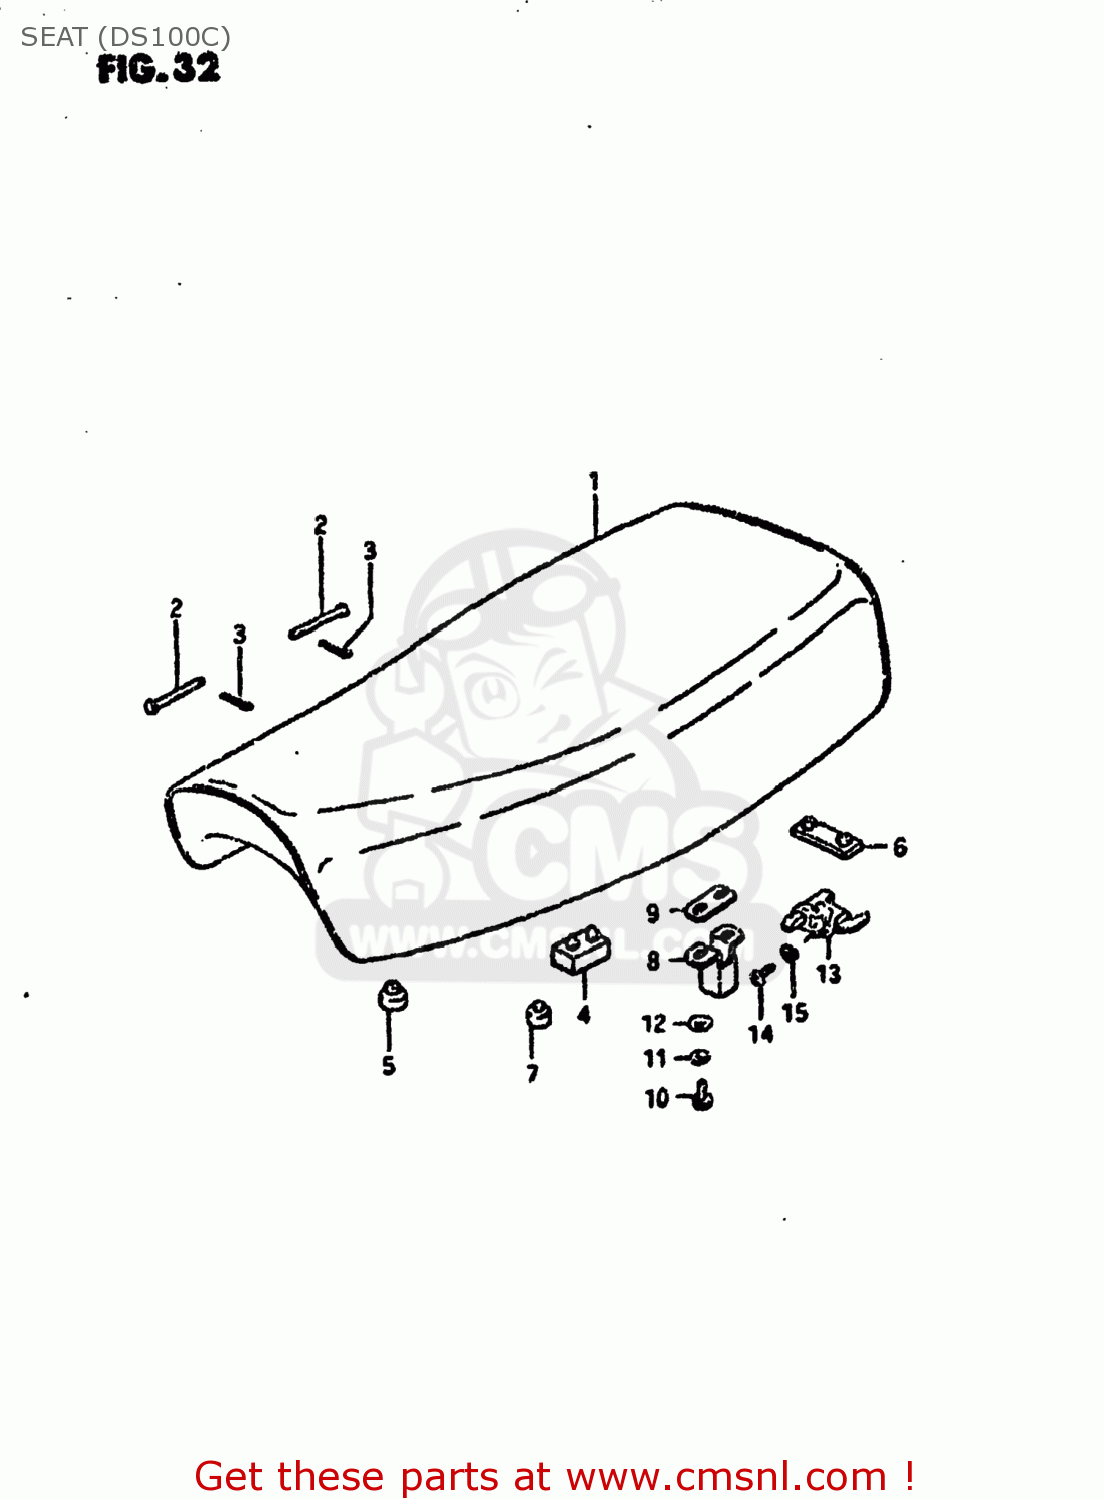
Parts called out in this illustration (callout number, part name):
1	SEAT ASSEMBLY
2	PIN
3	PIN
4	CUSHION
5	CUSHION(11.5X22X20)
6	CUSHION
7	CUSHION
8	PLATE,CLAMP GUIDE
9	SHIM,SEAT LOCK STRIKER
10	BOLT
11	LOCK WASHER
12	WASHER
13	LOCK ASSEMBLY,SEAT
14	SCREW
15	LOCK WASHER
